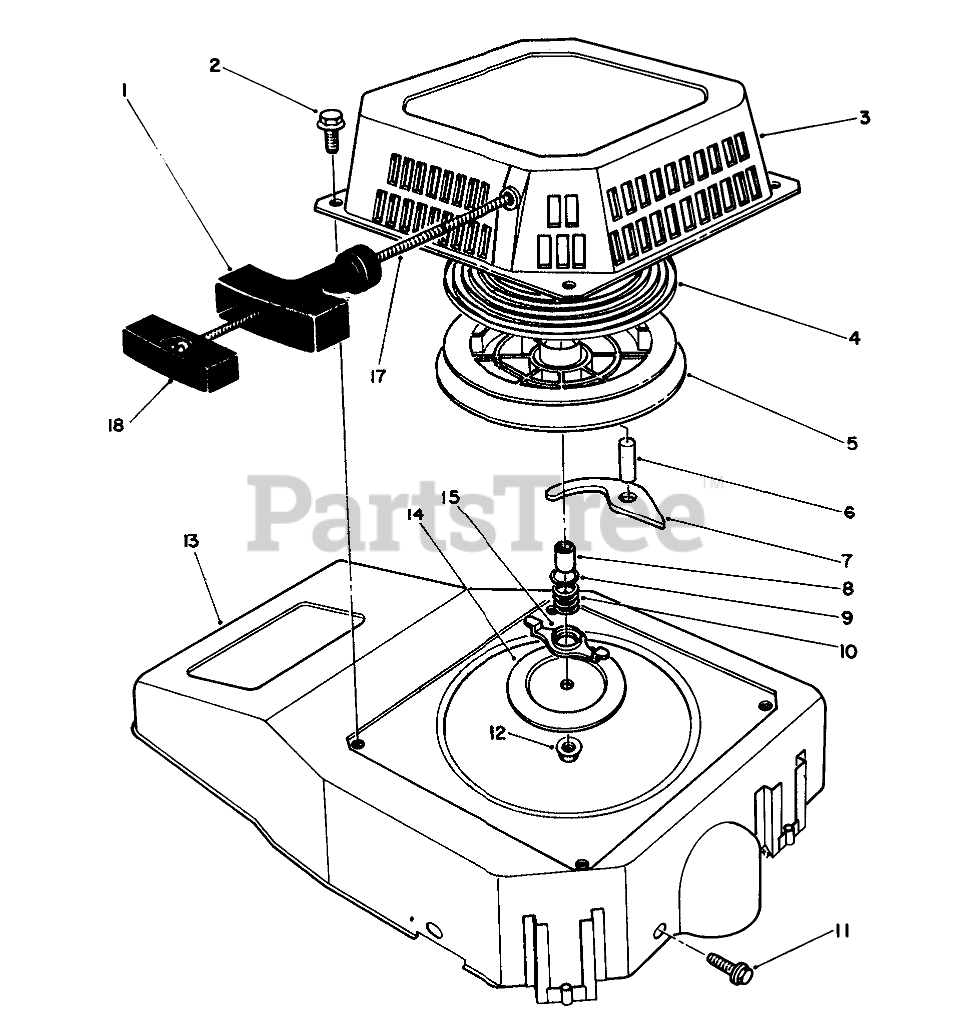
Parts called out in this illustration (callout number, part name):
1	HANDLE
2	SCREW-HHF
3	Case-Recoil
4	SPRING
8	Spacer
9	WASHER
10	Spring-Friction
13	SHROUD
14	PLATE
15	Guide-Paw
17	ROPE-STARTER
18	RETAINER HANDLE
